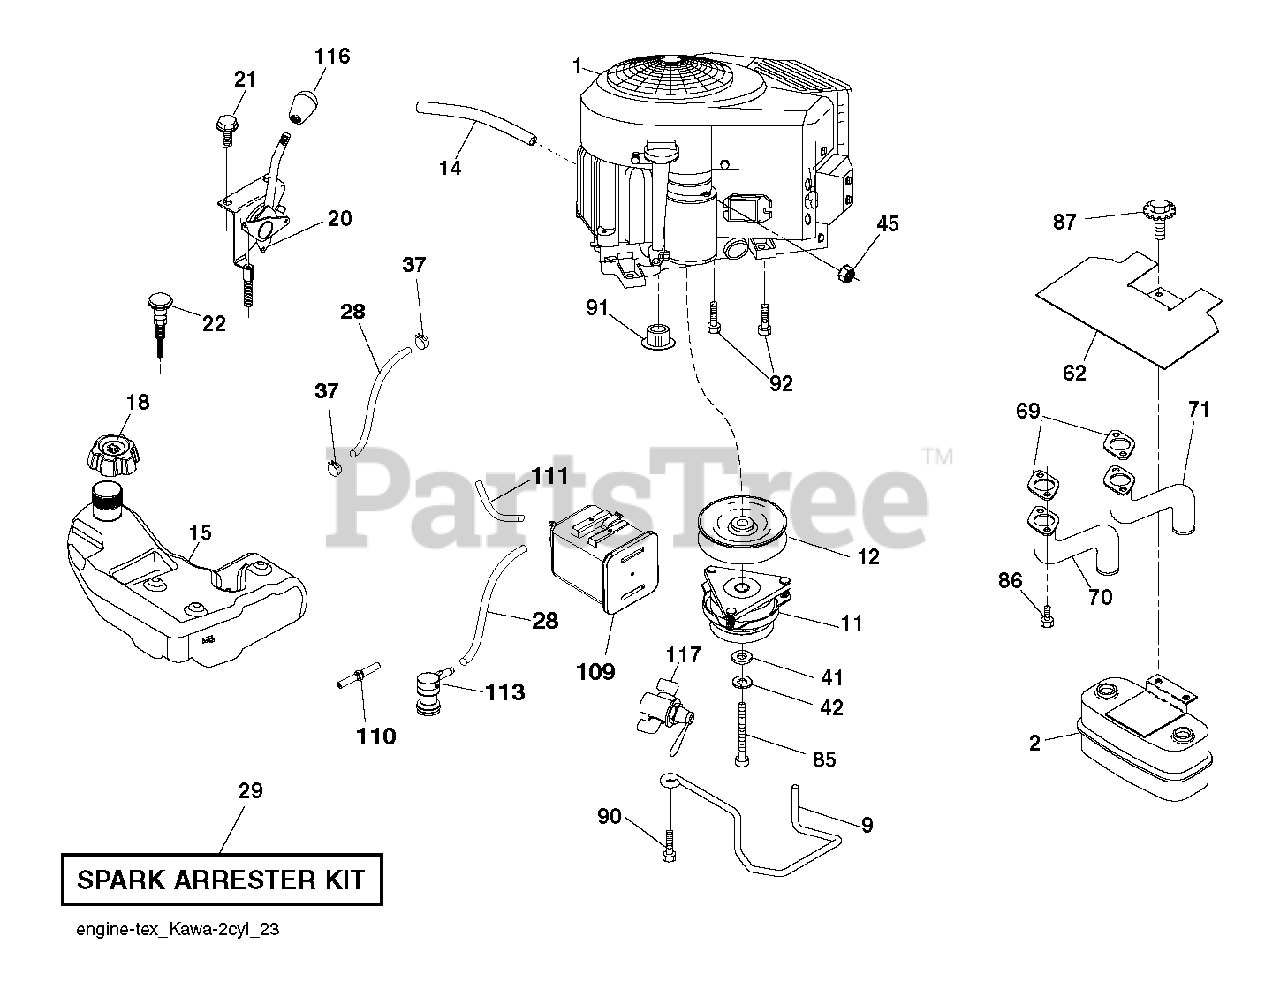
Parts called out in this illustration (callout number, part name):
2	MUFFLER.ASM.TWN.EXTNDED.DFLCTR
9	KEEPER.BELT.ENGINE.4.2
11	CLUTCH.ELECTRIC.LT.48"*
12	PULLEY.ENGINE.TUFFTORQ
14	TUBE, DRAIN OIL ASM.
15	TANK.ASSY.4.GAL.2.PORT.EPA
18	CAP.ASM.FL.RITCH.3"E10.SYM.498
20	CONTROL.THROTTLE.PRO.
21	SCREW.#10 X 0.750.BOS
22	CONTROL.CHOKE.ERGO.PUSH-IN.BLA
28	LINE.FUEL.64"REAR.EMIS
29	KIT.SPARK ARRESTOR 794945 B&S
37	HOSE CLAMP
42	LOCKWASHER
45	NUT
62	SHIELD.HEAT.MUFFLER
70	TUBE.EXHAUST.LH.FR961/FR730
71	TUBE.EXHAUST.RH.FR961/FR730
85	BOLT HEX 7/16-20X4-1/4"
86	NUT.HEX.FLANGE.TOPLOCK
87	Bolt, 5/16-18 X 1-3/4
90	SCREW 3/8-16X1
91	BUSHING.1.375OD
92	SCREW 3/8-16X1
109	CANNISTER, CARBON
110	VALVE.ASM.ANTI-SLOSH
111	PURGE.LINE.36"REAR.CALIFORNIA
113	VALVE.SLANT.CARTRDG.90 DEG.TEX
116	KNOB - SHIFT
117	VALVE FUEL RESERVE
